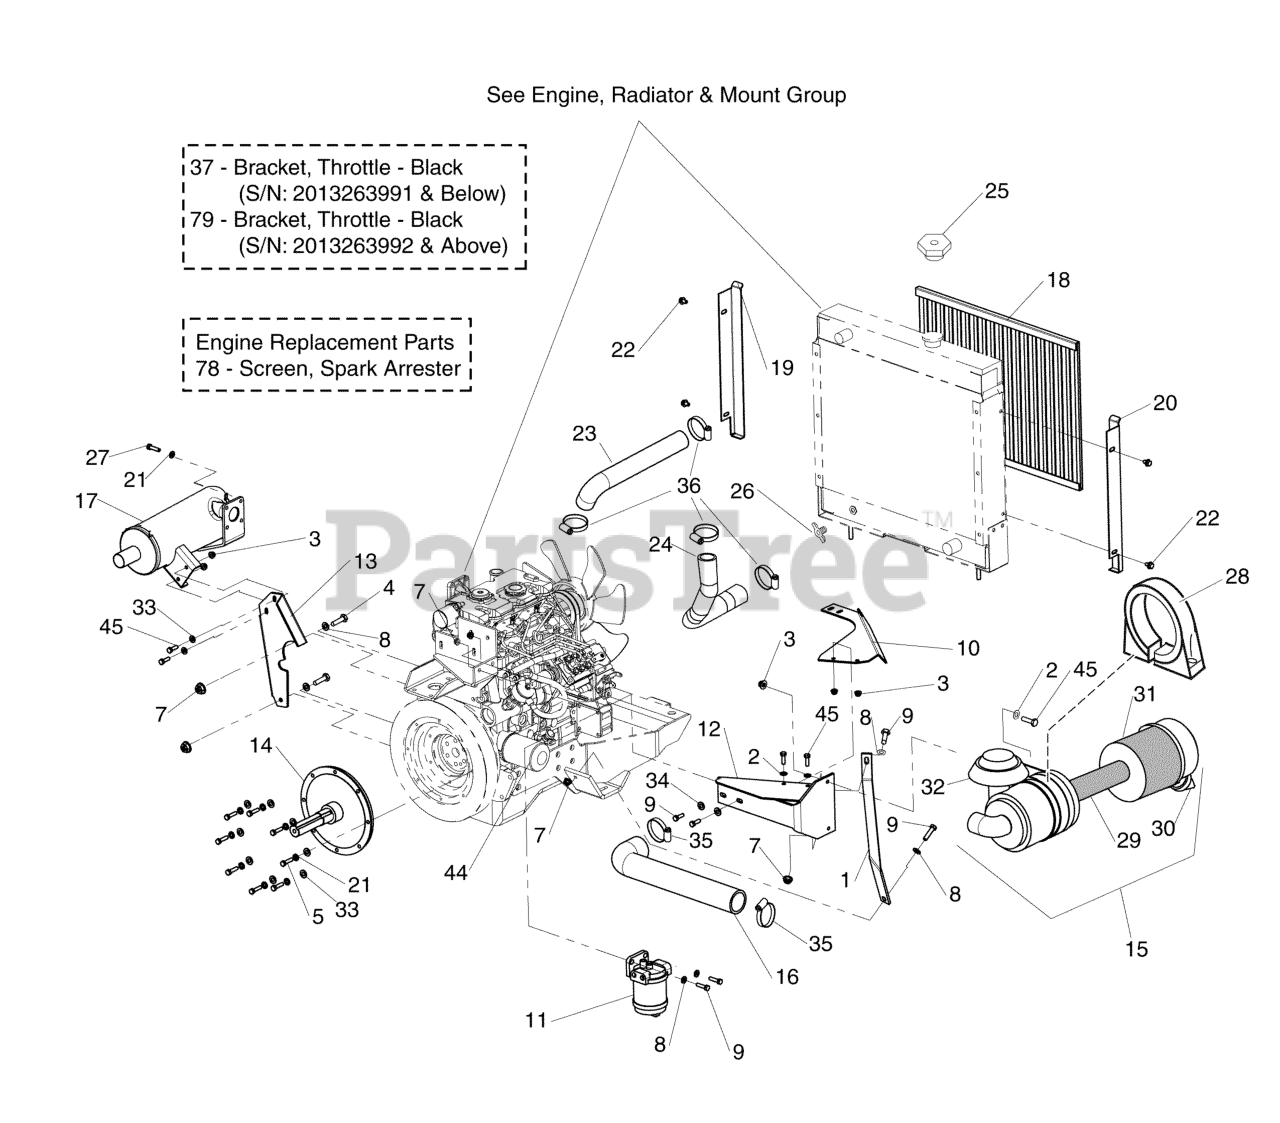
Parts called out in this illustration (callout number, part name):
1	SUPPORT, AIR FILTER - RED
2	WASHER, 5/16" SAE
3	NUT, 5/16-18 HEX NYLOCK FLANGE
4	BOLT, 3/8-16 X 1-3/4" GD5 CZ
5	BOLT, 5/16-18 X 1-1/4" GD5 YZ
7	NUT, 3/8-16 HEX NYLOCK FLANGE
8	WASHER, 3/8 SAE
9	BOLT, 3/8-16 X 1-1/4" GD5 CZ
10	PLATE, AIR FILTER - RED
11	FUEL FILTER ASSEMBLY (19B & 19C)
11	FUEL FILTER ELEMENT ONLY
12	WELD, AIR FILTER MOUNT
13	BRACKET, MUFFLER IS5000
14	* SHAFT, STUB, FLYWHEEL PLATE
15	AIR CLEANER ASSY
16	HOSE, AIR FILTER IS5000
17	MUFFLER, 3013C CAT ENGINE
18	SCREEN, FRONT,RAD, IS5000Z-DSL
19	BRACKET, RADIATOR SCREEN - LH
20	BRACKET, RADIATOR SCREEN - RH
21	WASHER, 5/16 LOCK CZ
22	BOLT, 5/16-18 X 1/2" FLANGE, SPEC
23	HOSE, UPPER RADIATOR CAT
24	HOSE, LOWER RADIATOR - CAT
25	CAP, RADIATOR - NET
26	PETCOCK VALVE
27	BOLT, M8-1.25 X 25MM GR 8.8
28	BRACKET, AIR CLEANER ASSY
29	AIR FILTER ELEMENT (SECONDARY)
30	AIR CLEANER DUST VALVE
31	ELEMENT ASSY
32	CAP, A/C RAIN
33	WASHER, 5/16" GD.9 FLAT
34	WASHER, 3/8" GD.9 FLAT
35	CLAMP, SS HOSE 2-3/4"
36	HOSE CLAMP
44	FILTER, ENGINE OIL
45	BOLT, 5/16-18 X 1" GD5 YZ
